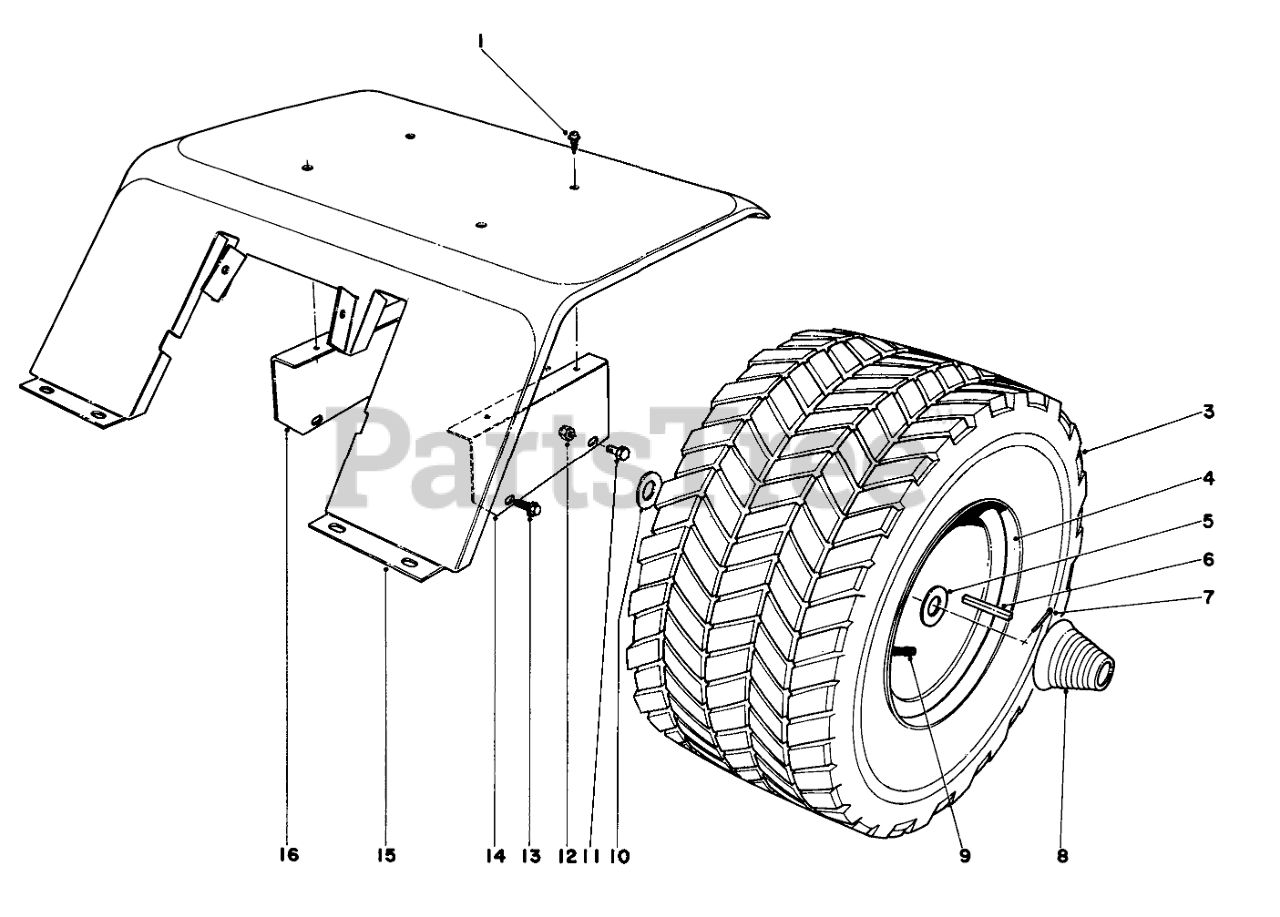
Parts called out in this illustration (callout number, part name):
1	10-16 X 3/8 THDG SCREW
5	WASHER-THRUST
7	PIN-COTTER
8	FRONT HUB CAP
9	VALVE -STEM
10	Washer-Special
11	SCREW-HH
12	NUT-LOCK, CONE
13	1/4-20X5/8 THDG SEMS
14	Fender Support L.H.
15	Fender
16	Fender Support R.H.
